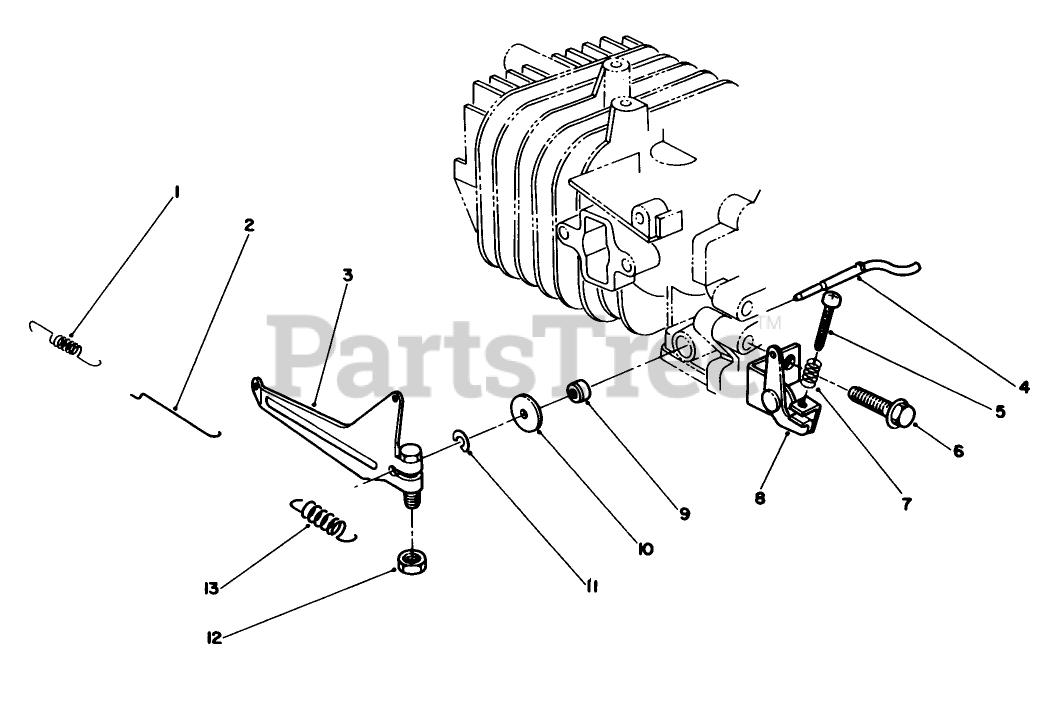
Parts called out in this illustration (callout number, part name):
2	CARB ROD
4	SHAFT
5	SCREW
7	SPRING
8	GOV SPR BRKT
9	SEAL-OIL
10	WASHER
13	GOV SPRING
